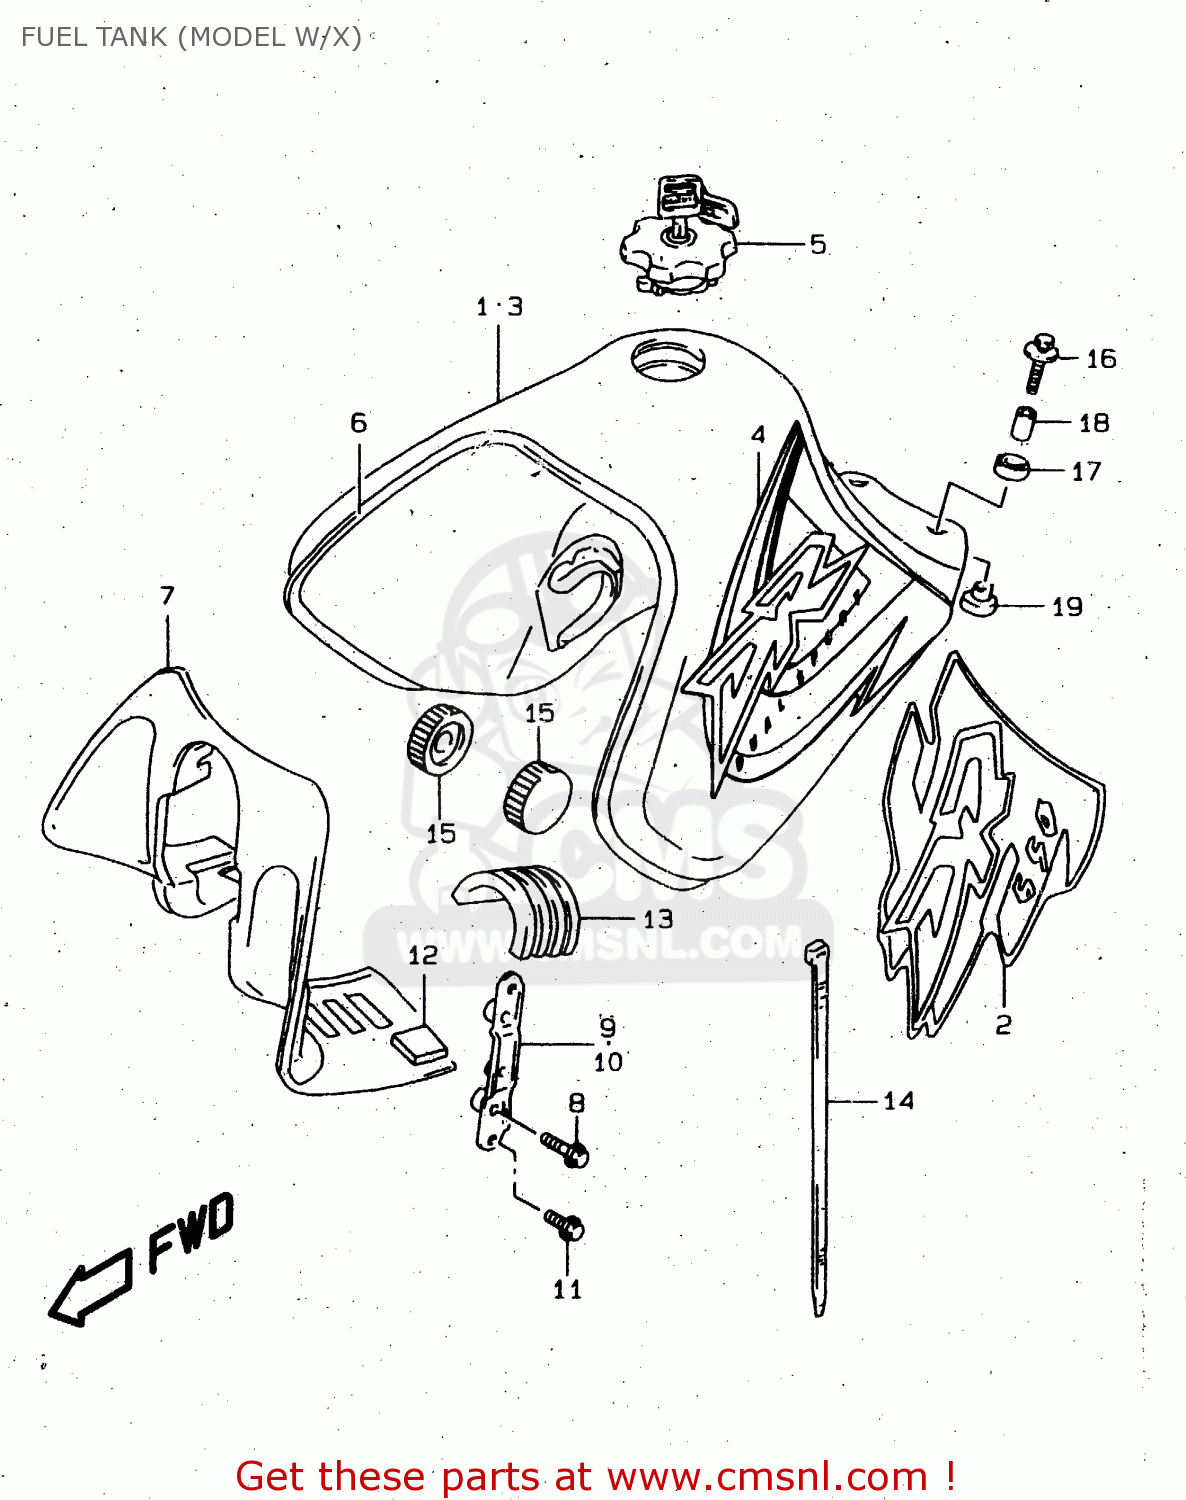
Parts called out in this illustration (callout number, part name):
1	TANK ASSEMBLY,FUEL
2	TAPE SET,FUEL TANK
3	TANK ASSY,FUEL(BLACK)
4	TAPE SET,FUEL TANK
5	CAP SET,FUEL TANK
6	MOLDING,FUEL TANK
7	COVER,FUEL TANK FR
8	BOLT 6X14
9	BRACKET,FUEL TANK COVER,R
10	BRACKET,FUEL TANK COVER,L
11	BOLT
12	CUSHION,HEADLAMP COVER
13	CUSHION,FUEL TANK UPR
14	CLAMP(L:250)
15	CUSHION,FUEL TANK FR
16	BOLT(6X30)
17	CUSHION
18	SPACER(6.5X9X18)
19	CUSHION
